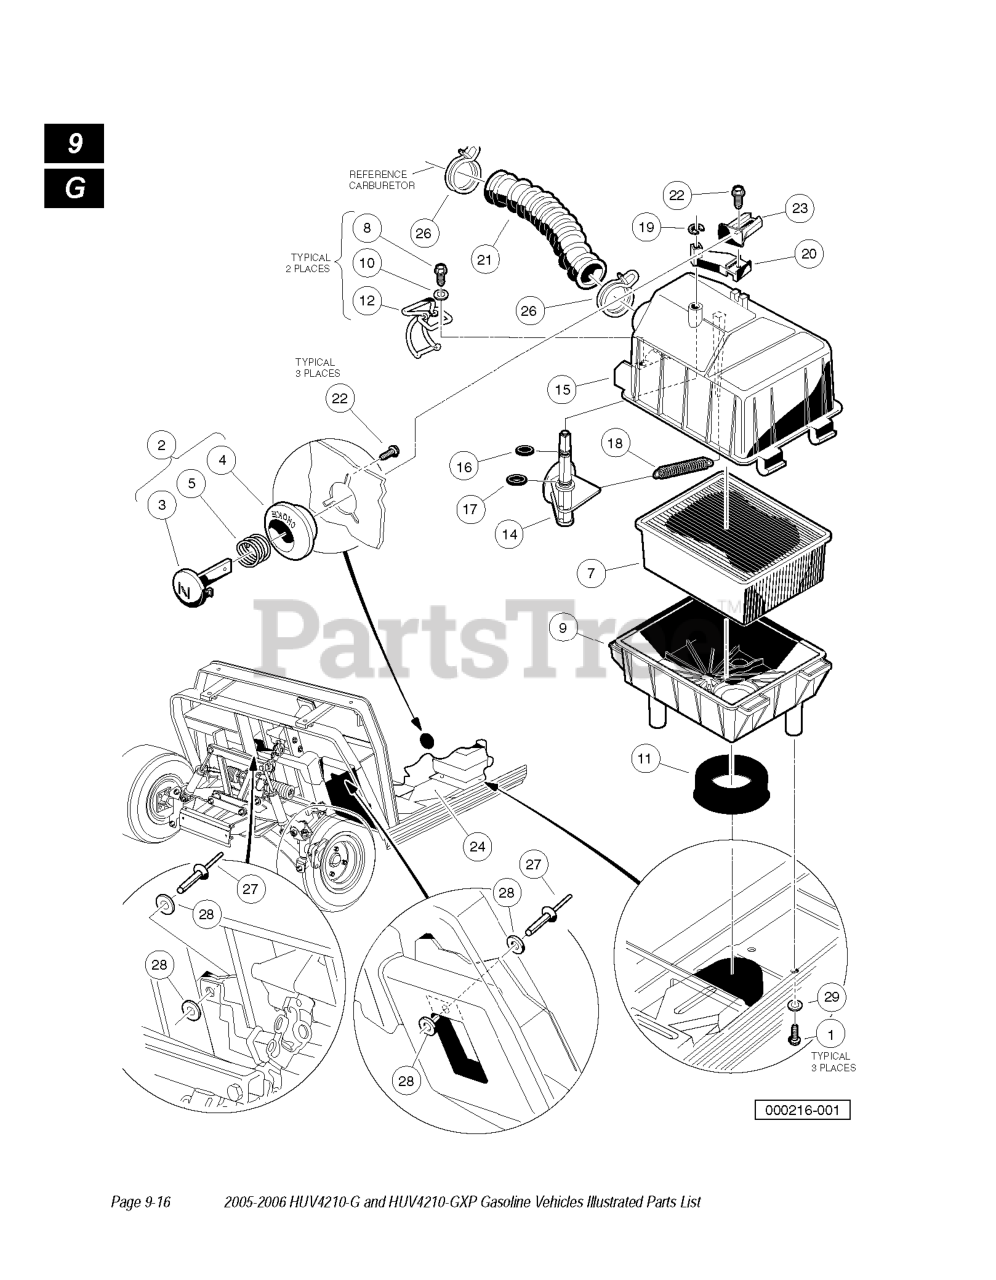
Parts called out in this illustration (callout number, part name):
1	SCREW, #12-16 X .625 HI-LO
2	BUTTON ASSY, CHOKE
3	LEVER, CHOKE
4	GUIDE, CHOKE LEVER
5	COMPRESSION SPRING
6	AIR BOX ASSY
7	AIR FILTER OHV
8	SCREW, #8 X .500 HX HD HI-LO
9	BOTTOM, AIR BOX
10	WASHER, #8 SS FLAT WASHER
11	SEAL, INTAKE
12	LATCH, WIREFORM
13	TOP ASSY, AIR BOX
18	SPRING, EXTENSION RETURN
19	RETAINING RING .25 SHAFT
20	LEVER, CHOKE
21	AIR INTAKE HOSE
22	SCREW, #12-16 X .50 WSHR HI-LO
23	CHOKE POSITIONER
24	DUCT ASSY, DS AIR
26	CLAMP, 1.58" ID HOSE
27	RIVET, 3/16 X .5 ALUM POP
28	WASHER FLAT
29	WASHER 1/4 FLAT
